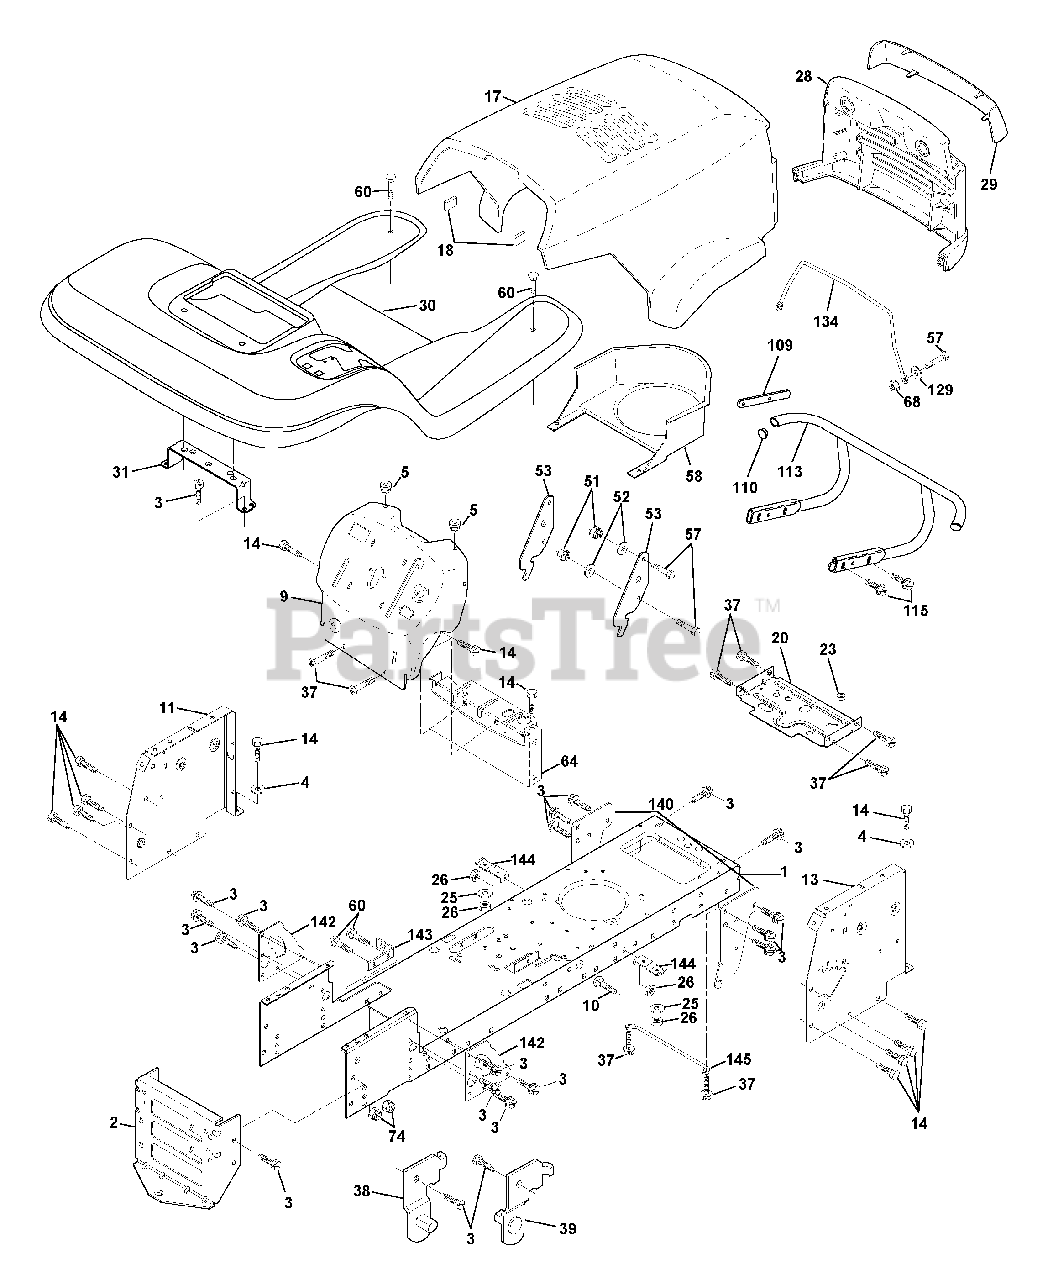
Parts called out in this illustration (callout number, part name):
1	Chassis Weldment
2	Drawbar, Stretch
3	Screw Thdrol 3/8-16x3/4 Ty-tt
4	Washer 13/32 x 3/4 x 16 Ga.
5	Bumper Hood/Dash
9	Dash Slkscr.Plm.E.A.Hm.Nc.Sym
10	Bolt Carriage 3/8-16 x 1
11	Panel Dash Lh
13	Panel Dash Rh
14	Screw Thdrol 3/8-16x1/2 Ty-tt
17	Hood LT/PL Husqvarna
18	Bumper Hood
20	Plate Mtg Battery Fuel Tank Fr
25	Washer 13/32 X 13/16 X 12 Ga
26	Nut Lock Hex W/Ins 3/8-16 Unc
28	Grille LT/PL Husqvarna
29	Lens LT/PL Husqvarna
30	Fender Footrest STLT Pnt
31	Bracket Support Fender
37	Screw Thdrol 6/16-18 x 1/2 TYT
38	Bracket, Asm. Pivot, L.H., Mower Rear
39	Bracket, Asm. Pivot, R.H., Mower Rear
51	Nut Lock Hex W/Ins 1/4-20
52	Washer 9/32 x 7/8 x 16 Ga.
53	Bracket Pnt. Pick off LT/PL Husqvarna
57	Bolt Hex 1/4-20 x 3/4
58	Air Duct Engine P/L
60	Bolt Rdhd Sqnk 3/8-16unc x 3/4
64	Dash Lower STLT
68	Nut Keps Hex 1/4-20unc
71	Nut Crownlock 1/4-20 UNC
74	Nut Crownlock 3/8-16 UNC
109	Bracket Extension Bumper
110	Plug Plastic
113	Bumper Asm.
115	Screw Thdrol 3/8-16 x 1-1/4
122	Bracket Shift Stlt
123	Screw TT #10-32.5.3/8 Flange
129	Washer 9/32 x 5/8 x 16 Ga.
134	Rod Support Hood LT/PL Husq.
140	Bracket Suspension Front
142	Plate Reinforcement STLT
143	Bracket Swaybar Chassis
144	Bracket Pnt Footrest STLT
145	Rod Pivot Chassis/Hood
147	Bolt Hex Hd 1/4-20 UNC 3/4
